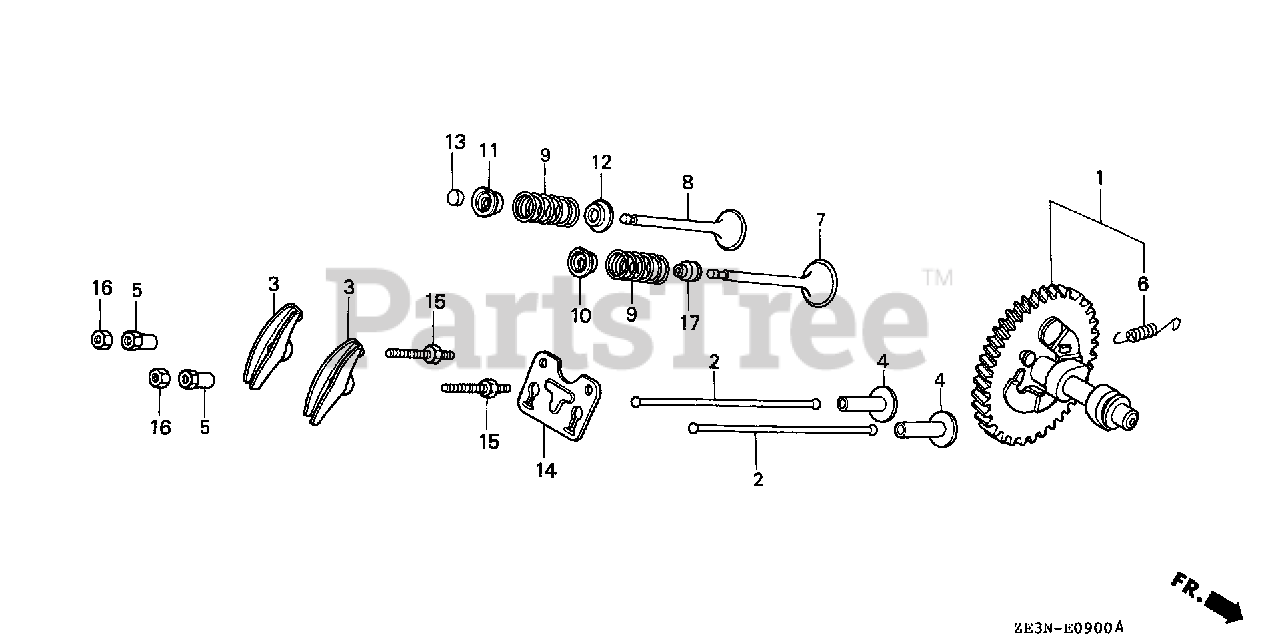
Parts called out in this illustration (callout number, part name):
1	CAMSHAFT ASSY.
2	ROD, PUSH
3	ARM, VALVE ROCKER
4	LIFTER, VALVE
5	PIVOT, ROCKER ARM
6	SPRING, WEIGHT RETURN
7	VALVE, IN.
8	VALVE, EX.
9	SPRING, VALVE
10	RETAINER, IN. VALVE SPRING
11	RETAINER, EX. VALVE SPRING
12	SEAT, VALVE SPRING
13	ROTATOR, VALVE
14	PLATE, PUSH ROD GUIDE
15	BOLT, PIVOT (8MM)
16	NUT, PIVOT ADJ.
17	SEAL, VALVE STEM
